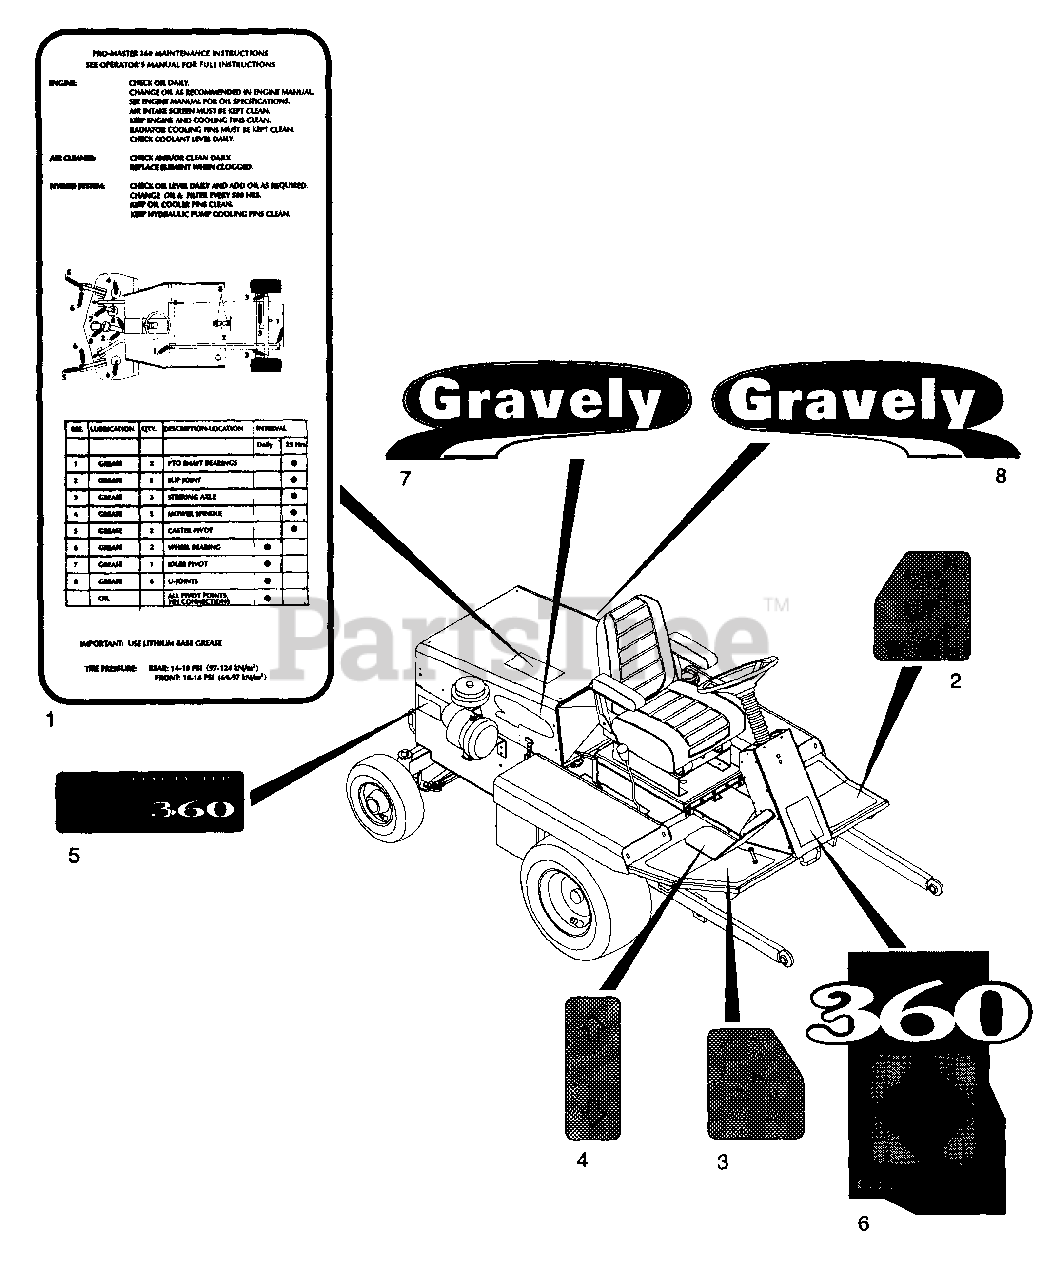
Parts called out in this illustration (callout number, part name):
1	Decal Set, PM 360 Warnings
2	Cover, Left Hand Foot
3	Cover, Right Hand Foot
4	Cover, Foot Pedal
5	Decal, PM-360
6	Decal, PM-360
7	Decal, Gravely Logo (R.H.)
8	Decal, Gravely Logo (L.H.)
